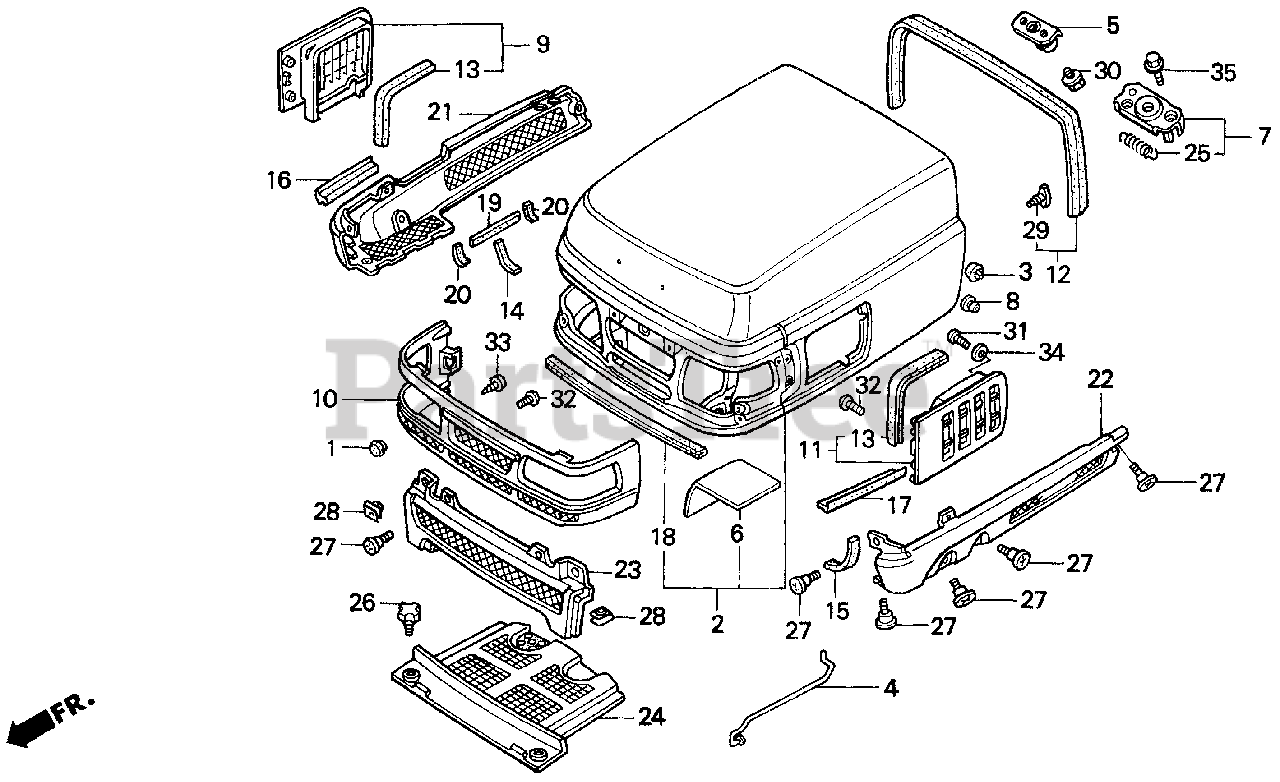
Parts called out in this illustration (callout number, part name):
1	PLUG, HANDLE COVER (LOWER)
2	HOOD ASSY. *R165* (JOLLY RED)
3	RUBBER, HOOD
4	STOPPER, HOOD OPEN
5	STRIKER ASSY., HOOD
6	HOOD GLASS WOOL
7	LOCK ASSY., HOOD
8	BUSH, STIFFENER
9	GARNISH, R. HOOD *NH105* (MAT BLACK)
10	GARNISH, FR. HOOD *NH105* (MAT BLACK)
11	GARNISH, L. HOOD *NH105* (MAT BLACK)
12	RUBBER, SHROUD SEAL (UPPER)
13	RUBBER, HOOD SEAL
14	RUBBER A, R. SIDE SKIRT SEAL
15	RUBBER, L. SIDE SKIRT SEAL
16	RUBBER, R. HOOD SEAL (LOWER)
17	RUBBER, L. HOOD SEAL (LOWER)
18	RUBBER, FR. SKIRT SEAL
19	RUBBER B, R. SIDE SKIRT SEAL
20	RUBBER C, R. SIDE SKIRT SEAL
21	SKIRT, R. SIDE *R165* (JOLLY RED)
22	SKIRT, L. SIDE *R165* (JOLLY RED)
23	SKIRT, FR. *R165* (JOLLY RED)
24	TRAY, BATTERY (LOWER) *R165* (JOLLY RED)
25	SPRING, HOOD LOCK
26	BOLT, SETTING (6MM)
27	SCREW, METER VISOR SETTING
28	NUT, CLIP (6MM)
29	CLIP, HOOD SEAL
30	BOLT-WASHER (6X12)
31	SCREW, PAN (5X6)
32	SCREW-WASHER (5X12)
33	SCREW, TAPPING (4X12)
34	WASHER, PLAIN (5MM)
35	BOLT, FLANGE (6X10)
